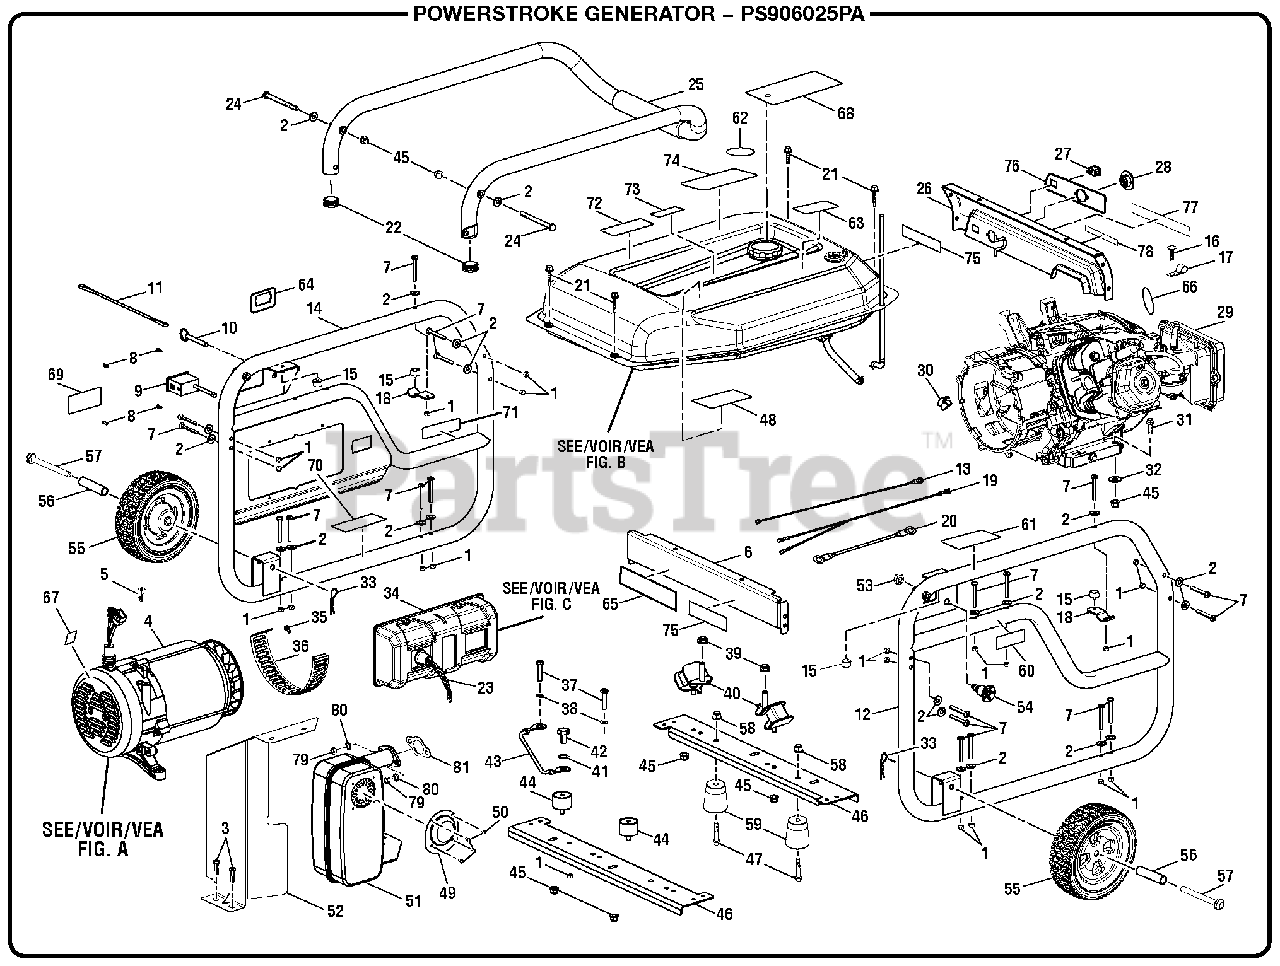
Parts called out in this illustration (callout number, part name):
1	Lock Nut (M6)
2	Washer (1/4 in.)
3	Bolt (3/8 in. x 3/4 in.)
4	Generator Head Assembly (See Figure A)
5	Ground Lug (1/4-20)
6	Fuel Tank Support (Rear)
7	Screw (M6 x 50 mm, Pan Hd.)
8	Screw (6-20 x 3/8 in.)
9	Analog Hour Meter
10	Pin Release
12	Frame (Left)
13	Off Switch Wire Assembly (Black)
14	Frame (Right)
15	Rubber Bumper
18	Handle Bracket
19	Wire Assembly Wire (Green)
20	Bonding Wire
21	Screw (1/4-14 x 1.25 in.)
22	End Cap (Handle)
23	Wire Sleeving
24	Screw (M8 x 98 mm, Flat Hd.)
25	Handle Assembly
26	Fuel Tank Support (Front)
27	On/Off Switch
28	Fuel Valve Bezel
30	Rubber Plug
31	Bolt (M8 x 40 mm, Hex Hd.)
32	Washer (5/16)
33	Hitch Pin
34	Control Panel Assembly (See Fig. C)
35	Bolt (M5 x 10 mm, Hex Hd.)
36	Fan Cover
37	Bolt (M8 x 1.25 in., Hex Hd.)
38	Lock Washer (M8)
39	Lock Nut (M10)
40	Isolator (Large)
41	Star Washer (M8)
42	Bolt (M6 x 16 mm, Flange Hd.)
43	Ground Wire Assembly
44	Isolator (Small)
45	Flange Nut (M8)
46	Reversible Cross Plate
47	Bolt (M8 x 45 mm, Hex Hd.)
48	Combustion Label
49	Spark Arrestor Screen
50	Screw (8-32 x 3/8 in., Pan Hd.)
52	Heat Shield
53	Hex Nut (1/2-20)
54	Handle Lock Assembly
58	Lock Nut (M8 x 1.25)
59	Rubber Foot
60	Hot Surface Label
61	Handle Release Label
62	Fuel Stabilizer Label
63	Danger Label
64	Systems Monitor Label
65	Ground Warning Label
66	Recoil Housing Label
67	Ground Label
68	Warning Hang Tag
69	Lock and Pin Label
70	Lubricant Label
71	Inquires label
72	Fire Danger Label
73	E85 Label
74	CPSC Label
75	Fire Distance Label
76	Fuel Label
77	Logo Label
78	Start Label
81	Muffler Gasket
